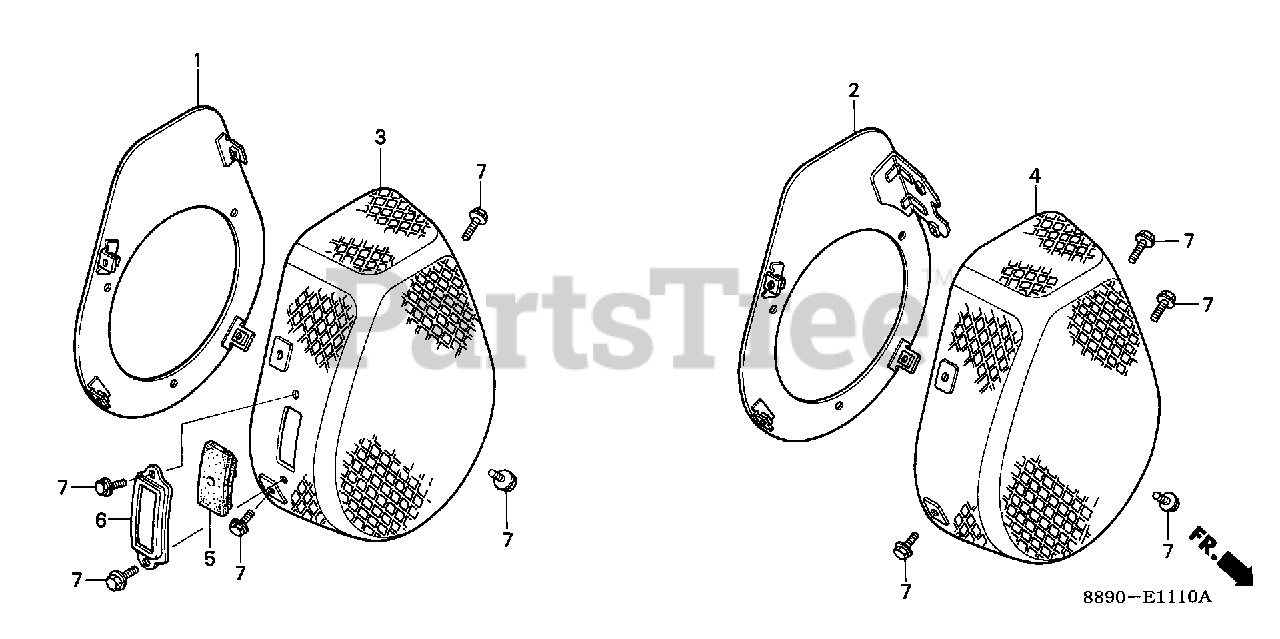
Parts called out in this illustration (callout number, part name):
1	BASE, DUST COVER
3	COVER, DUST (NOT AVAILABLE)
5	GUIDE, ROPE
6	RIM, ROPE GUIDE
7	BOLT, FLANGE (6X10)
